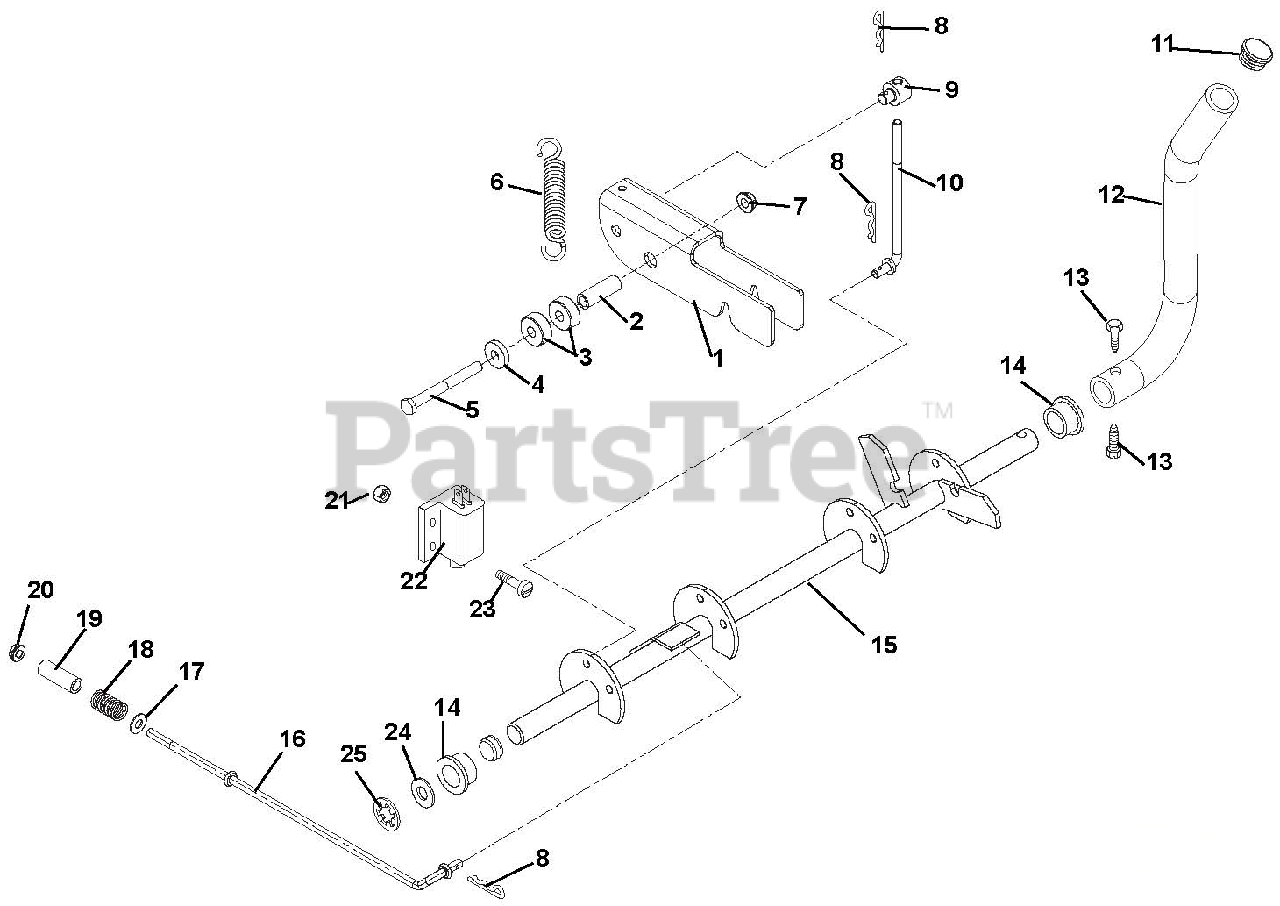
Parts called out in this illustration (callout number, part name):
1	LATCH,NEUTRAL
2	BSHG-SLV .334 X .502 X 1.437
3	SPACER, .344X1.00X.410
4	WSHR-FL-STL .328X.87X.179 YWZC
5	@BLT-HEX .31-18X3.00 GR5 YWZC
6	SG-TENS .069X.62X3.50 WLD20
7	@NUT-LK-NYL-FLG .31-18 YWZC
8	PIN-HAIR INT .08X.18X1.18 YWZC
9	TRUNNION, BRAKE .31-18 UNC
10	BRAKE LINK
11	CAPLUG, HANDLEBAR
12	HANDLE,PARK BRAKE
13	@SCR-TAP .31-18X.50 HWH TR YWZ
14	BSHG-FLG .750X1.000X.625X1.250
15	WMT,BRAKE SHAFT
16	BRAKE LINK
17	@WSHR-FL-STL.312X.734X.065 YWZ
18	SG-COMP .045X.50X1.187
19	BSHG, SPCR .330X.500X1.01 PM
20	@NUT-LK-NYL .250-20 YWZC
21	@NUT-LK-NYL 10-24 W/INSRT YWZC
22	SWITCH- DOUBLE POLE N.O./N.O.
23	@SCR-MCH 10-24X.75 HWH YWZC
24	WSHR-FL-STL .755X1.25X.125 YZ
25	RG-RTNG 1.000X.748
